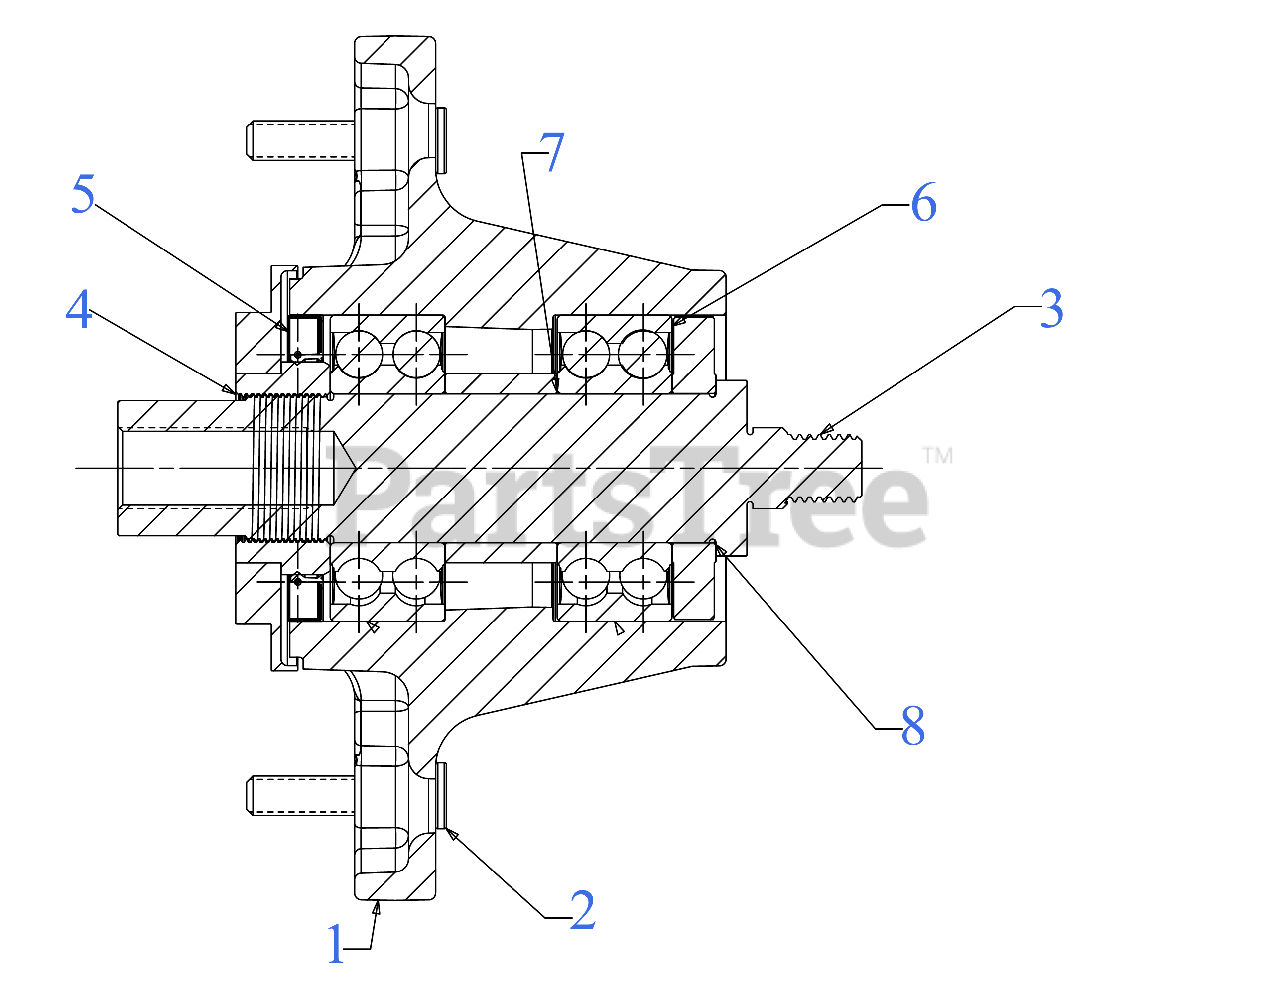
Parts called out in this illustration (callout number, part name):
1	SPINDLE HOUSING
2	STUD 3/8-16 x 1.75
3	SPINDLE SHAFT
4	SHOULDER NUT 1.375-18
5	SEAL 50 x 72 x 8
6	BEARING 35 x 72 x 27
7	SPACER 1.38 x 1.75 x 1.03
8	SPINDLE SHIELD
